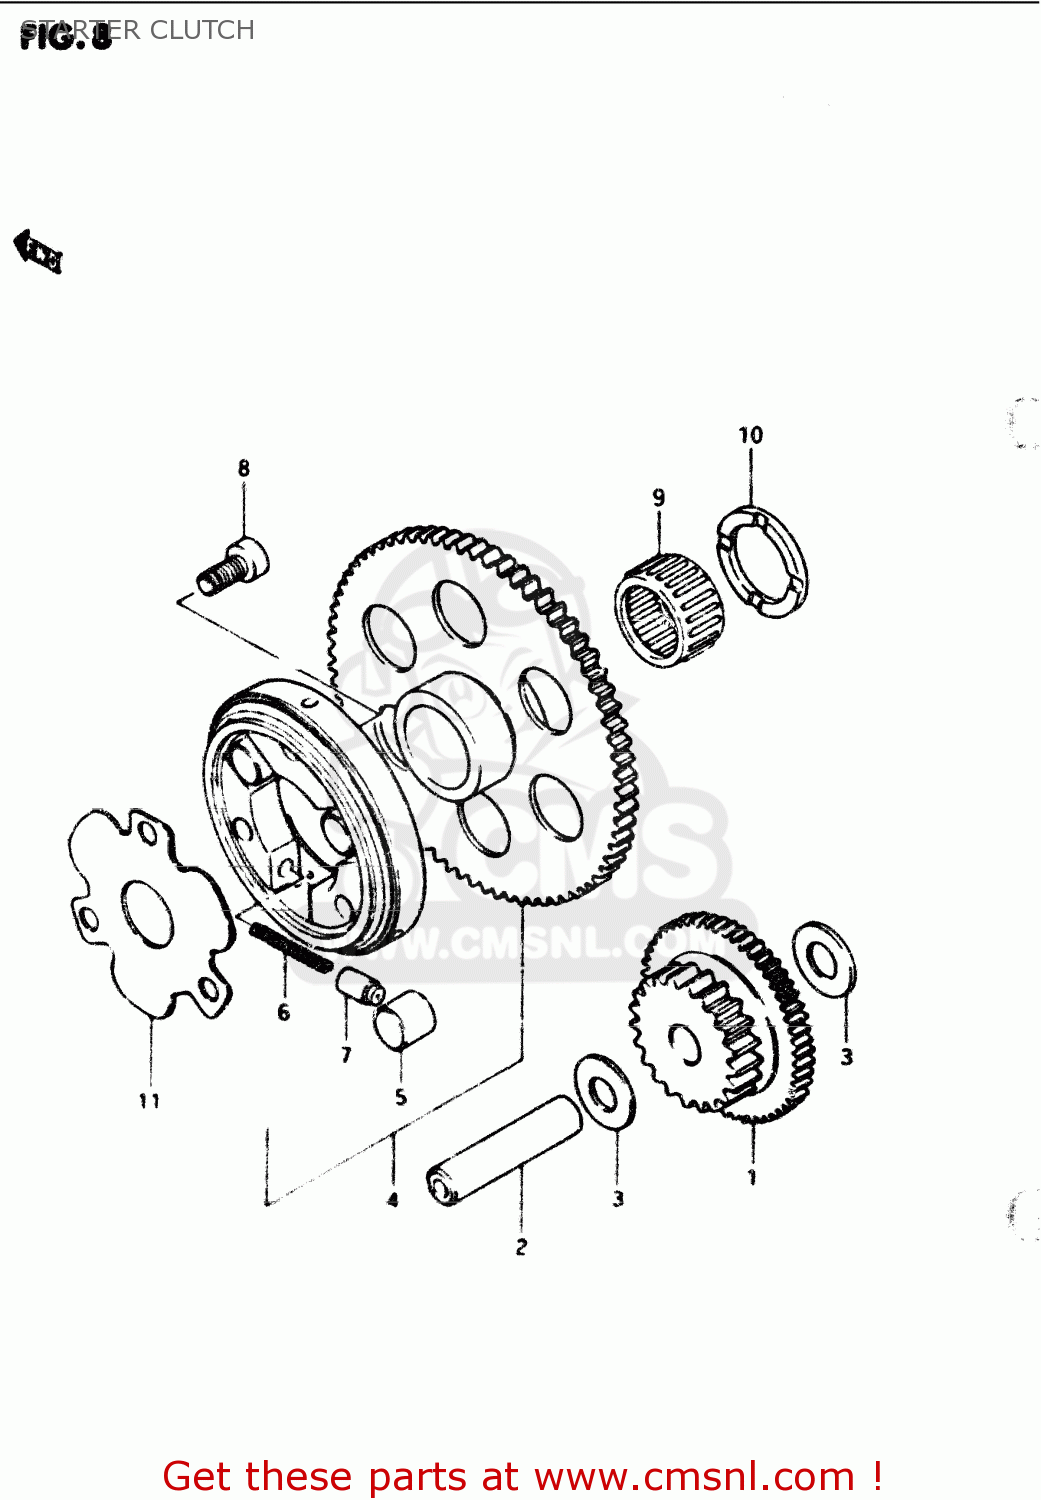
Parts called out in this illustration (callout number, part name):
1	GEAR,STARTER IDLE
2	PIN(7.4X13X56)
3	WASHER(13.3X25X0.85)
4	CLUTCH SET,STARTER
5	PIN(14X13)
6	SPRING
7	PIECE,PUSH
8	BOLT
9	ROLLER BEARING (25X31X2
10	WASHER(25X38X2.5)
11	SHIM,STARTER CLUTCH HUB
